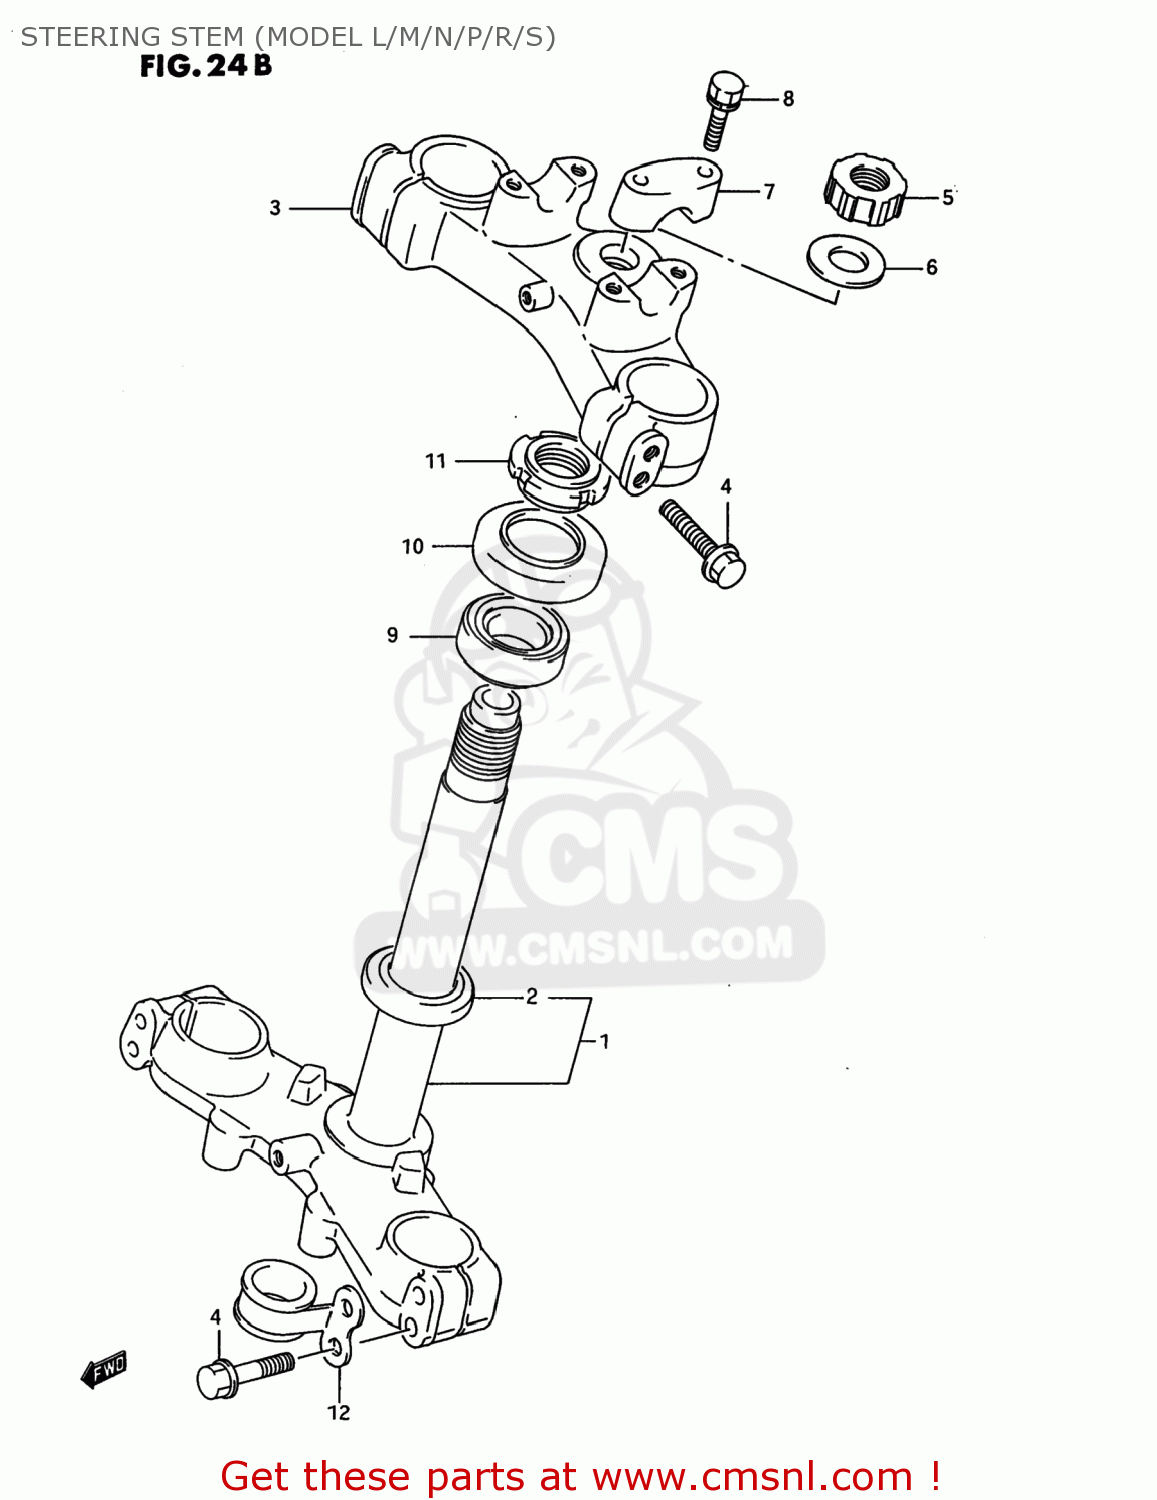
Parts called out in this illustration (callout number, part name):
1	STEM,STEERING
2	BEARING(26X47X15)
3	HEAD,STEERING STEM
4	BOLT
5	NUT,STEM HEAD
6	WASHER
7	HOLDER,HANDLEBAR
8	BOLT
9	TAPER,ROLLER BEARING
10	SEAL,STEERING UPR DUST
11	NUT,STEERING
12	CLIP
